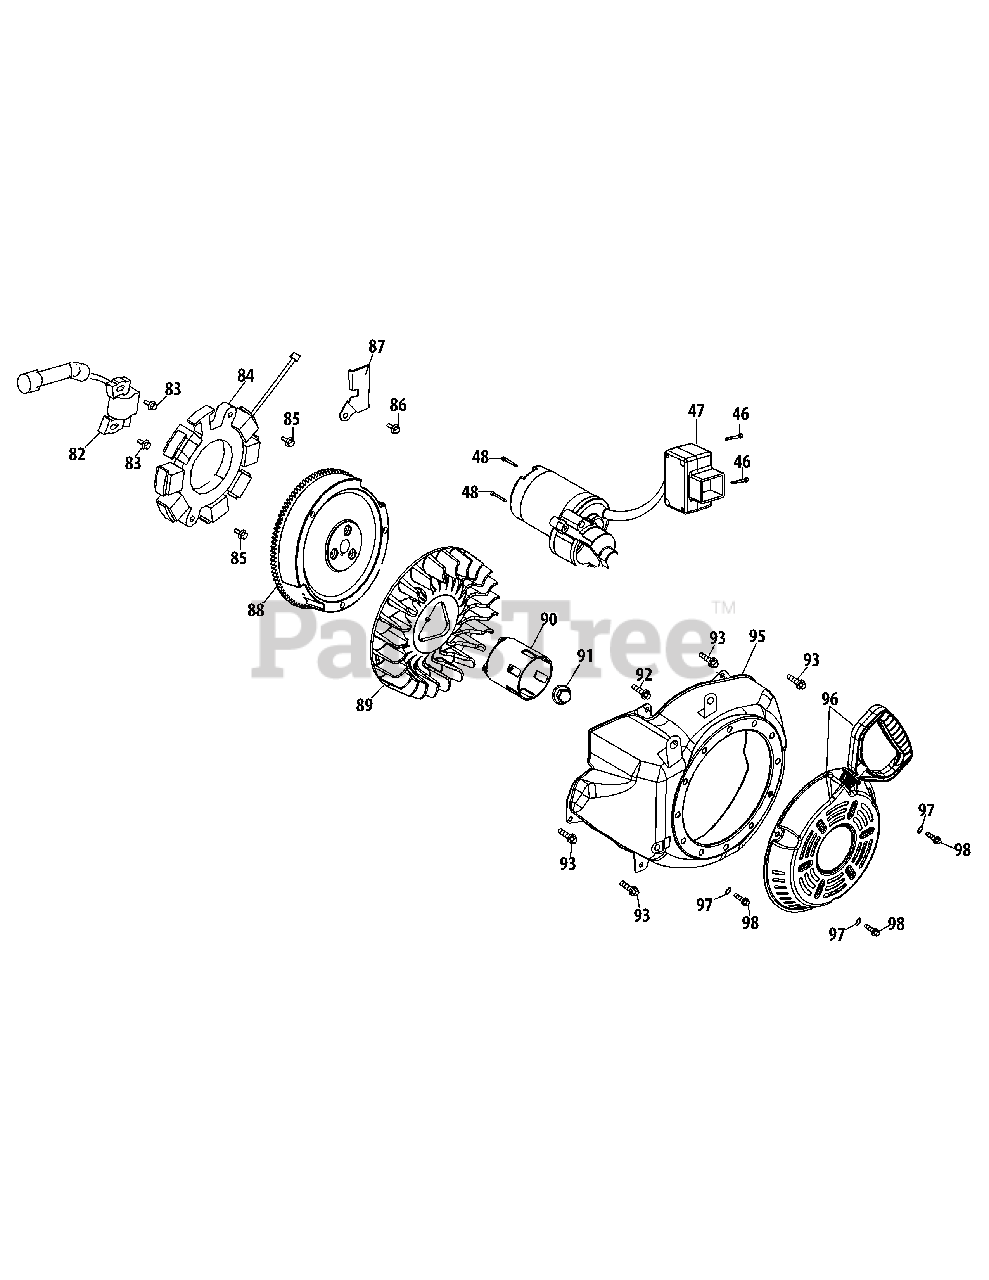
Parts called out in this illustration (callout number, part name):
46	Bolt M4×55
47	Electric Starter
48	Bolt M8×55
82	Ignition Coil Assembly
83	Ignition Coil Bolt
84	Coil Assy., Charge
85	Bolt M6×30
86	Bolt M6×8
87	Alternator Wire Clamp Brkt
89	Fan, Cooling
90	Pulley, Starter
91	Nut, Special, M16×1.5
92	Bolt M6×16
93	Bolt M6×12
95	Blower Housing
96	Recoil Starter
97	Gasket 6
98	Bolt M6×10
